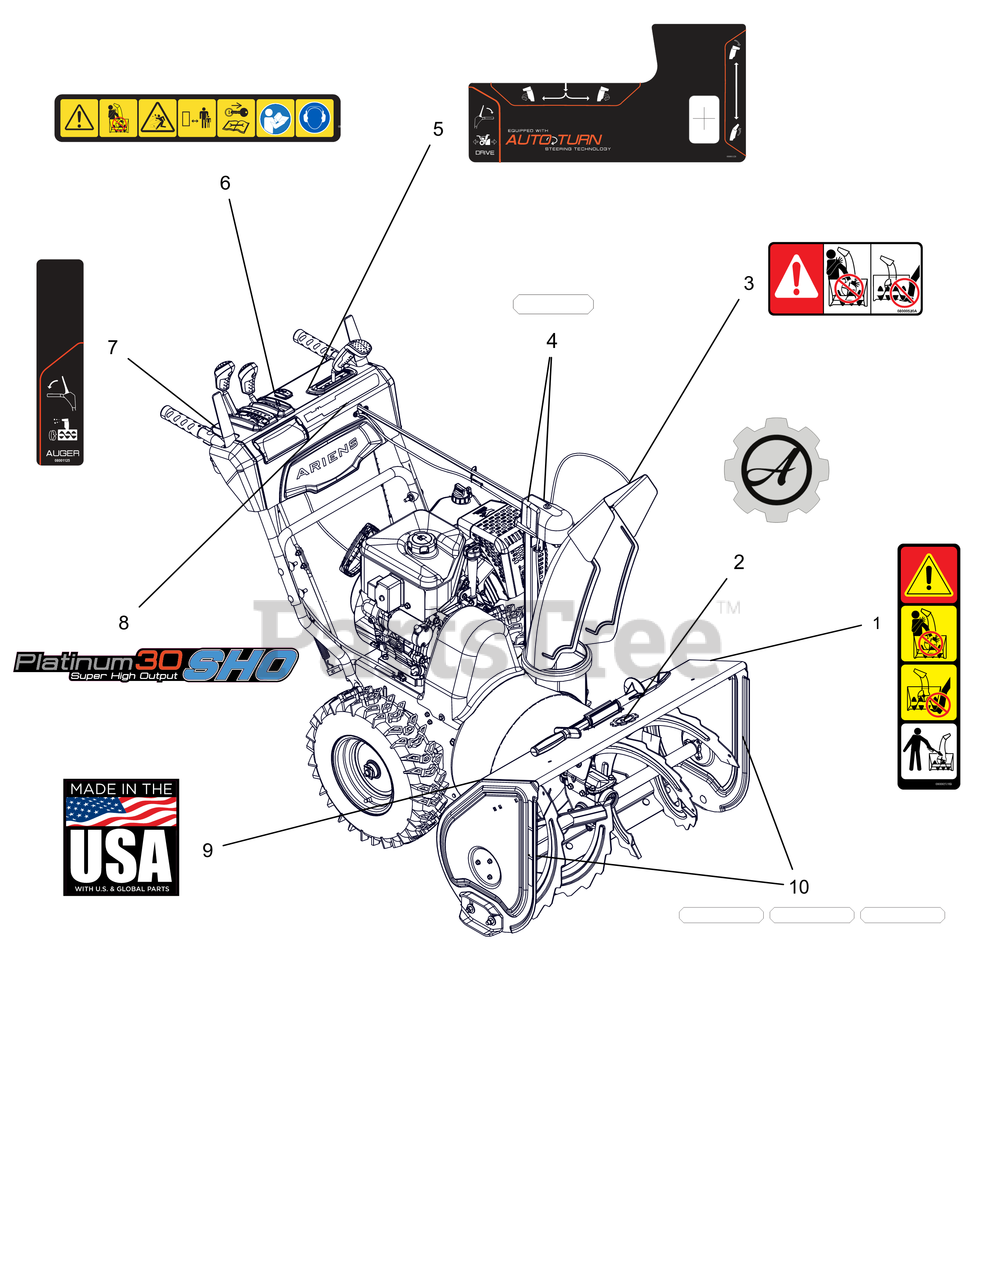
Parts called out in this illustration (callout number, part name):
1	DECAL, DANGER - ROTATING PARTS
2	DECAL, ARIENS-GEAR BADGE -THK
3	DECAL, DANGER
4	DECAL,REFLECTIVE,GEAR COVER
5	DECAL,CONTROL-LG QT2
6	DECAL,DASH - SAFETY
7	DECAL,CONTROL-RH CONTROL
8	DECAL, DASH, PLATINUM 30 SHO
9	DECAL, MADE IN USA
10	DECAL,REFLECTIVE,HOUSING
